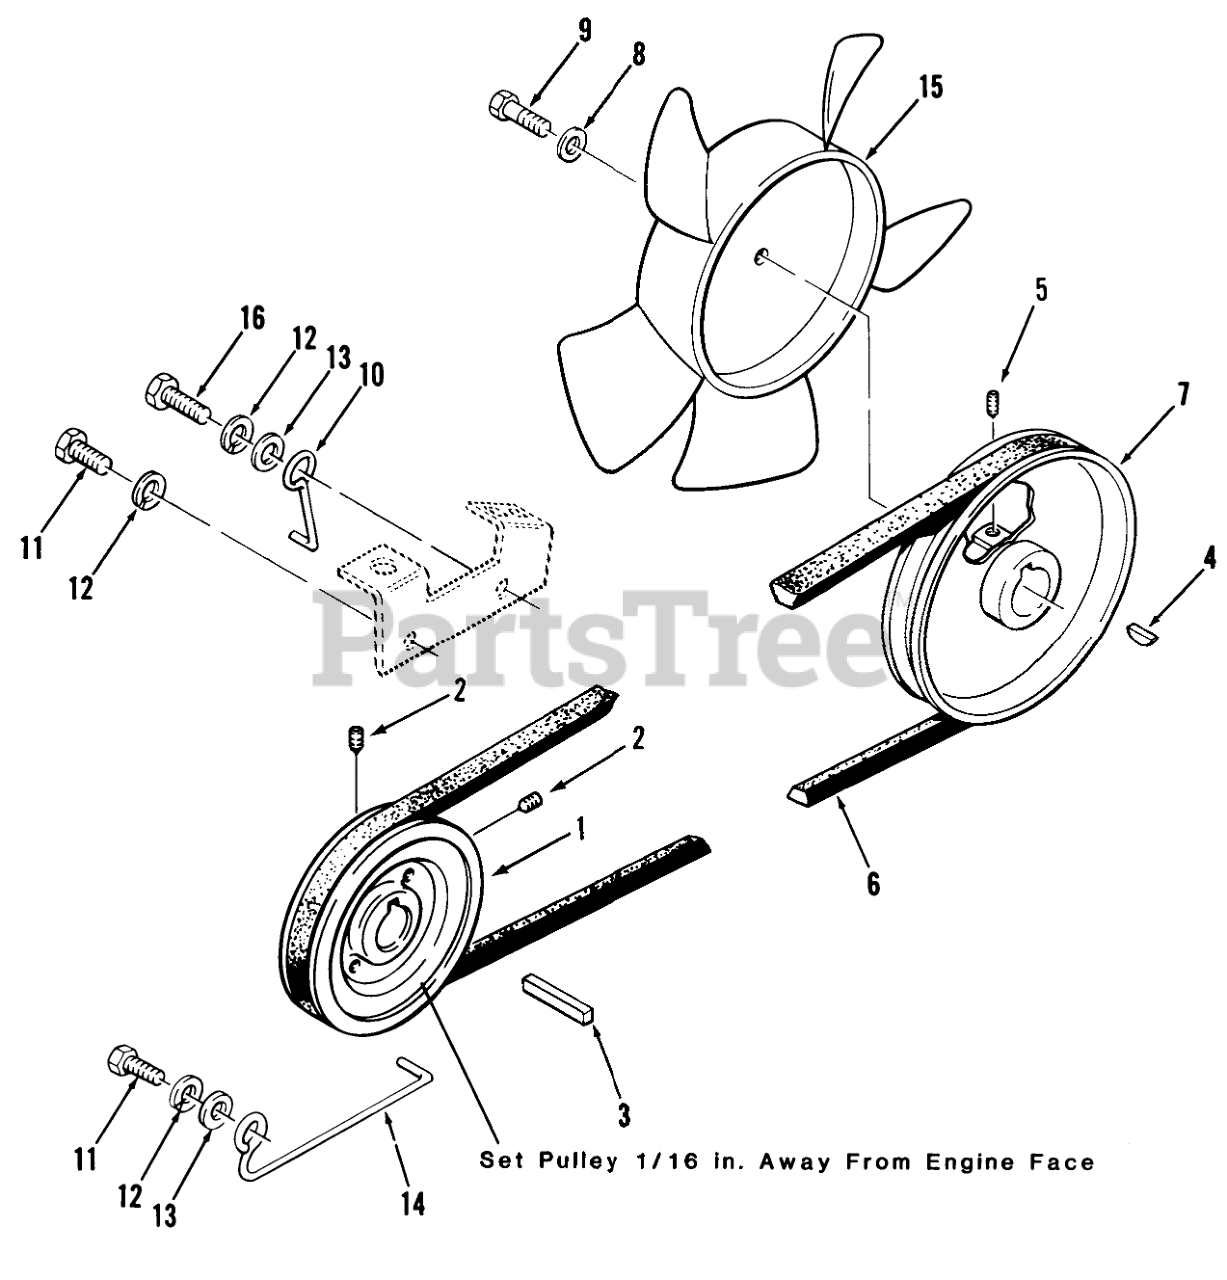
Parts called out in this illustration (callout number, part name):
1	PULLEY
2	Set Screw
4	KEY WOODR 1/8X1/2 DI
4	KEY-HI PRO
5	V-BELT TRANS DRIVE
5	Set Screw
6	V BELT
7	SHEAVE HYDRO INPUT
7	PULLEY-TRANSMISSION
8	WASHER
9	HEX HD CAP SCREW -4
10	GUIDE BELT TOP
11	7/16-14 x 1 1/4 Bolt
11	Bolt
12	LOCKWASHER
13	WASHER
13	Washer
14	GUIDE BELT
14	Belt Guide-Bottom 308-8 Only
15	NYLON FAN-L-CW
16	7/16-14 x 1 1/4 Bolt
16	Bolt
